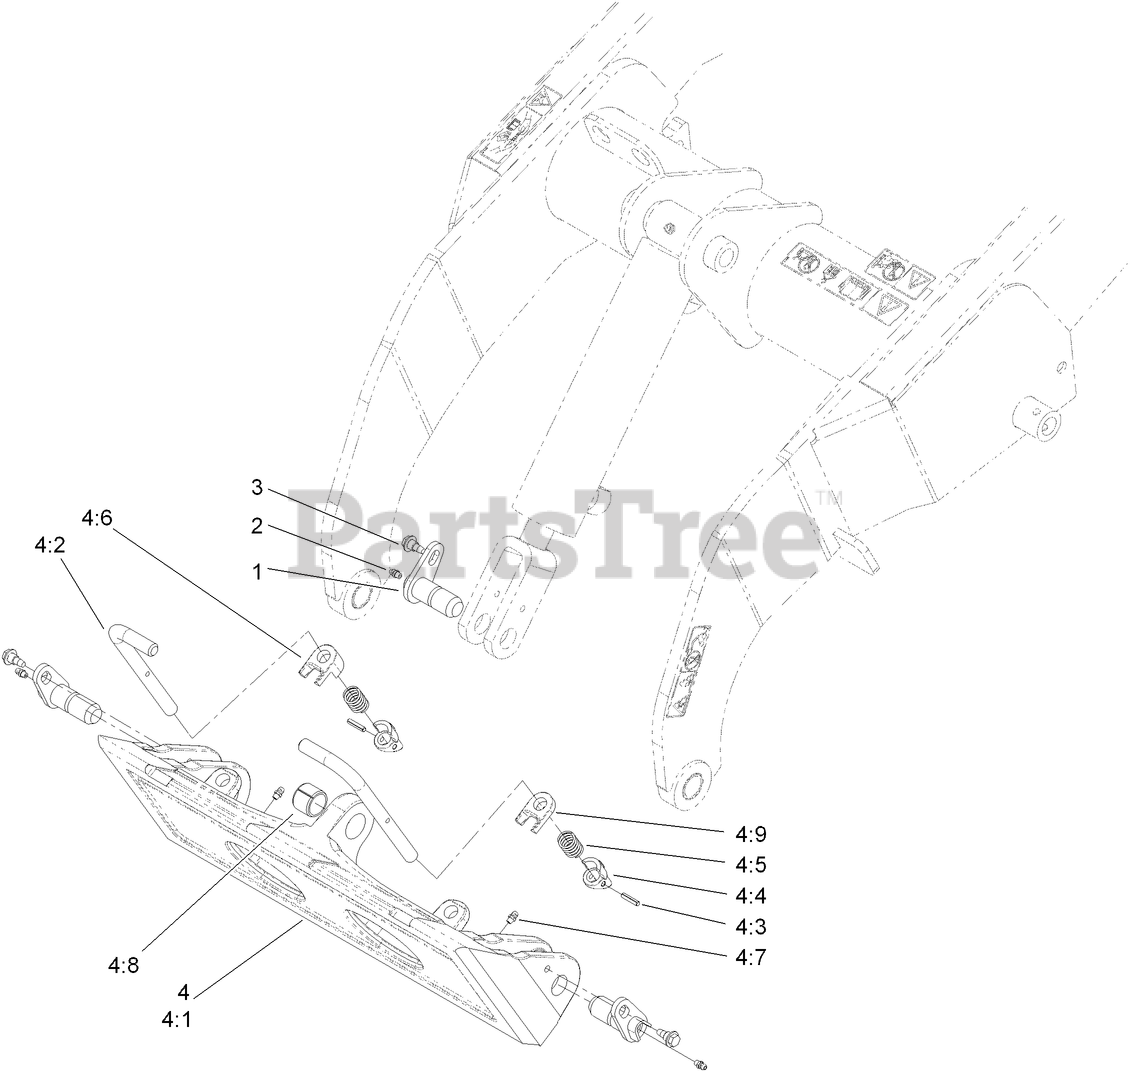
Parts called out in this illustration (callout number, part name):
1	PIN-PIVOT
2	FITTING-GREASE
3	BOLT-SHOULDER
4	QUICK ATTACH ASM
4:1	MOUNT-QTACH
4:2	PIN-LOCKING
4:3	PIN-GROOVED
4:5	SPRING-COMPRESSION
4:6	STOP-RH
4:7	FITTING-GREASE
4:8	BUSHING-TENSION
4:9	STOP-LH
